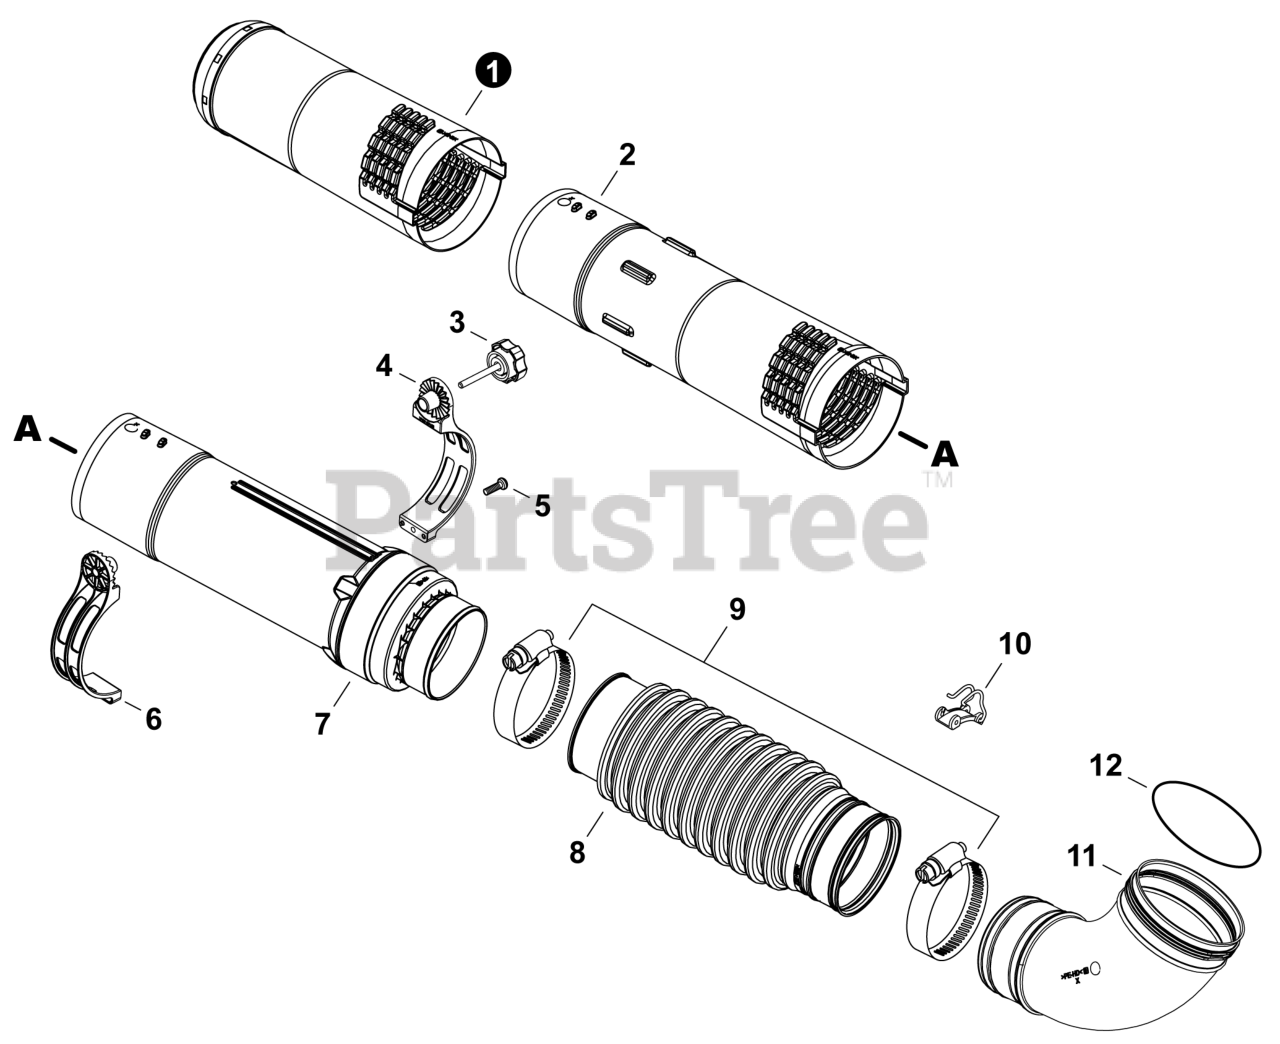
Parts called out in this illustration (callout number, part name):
1	TUBE, BLOWER - NOZZLE
2	TUBE, BLOWER - STRAIGHT
3	KNOB, SCREW
4	BRACKET, HANDLE - RIGHT
5	BOLT, TORX 5x20
6	BRACKET, HANDLE - LEFT
7	TUBE, BLOWER - SWIVEL
8	TUBE, BLOWER - FLEXIBLE
9	CLAMP - BAND
10	CLIP, CABLE
11	TUBE, BLOWER - ELBOW
